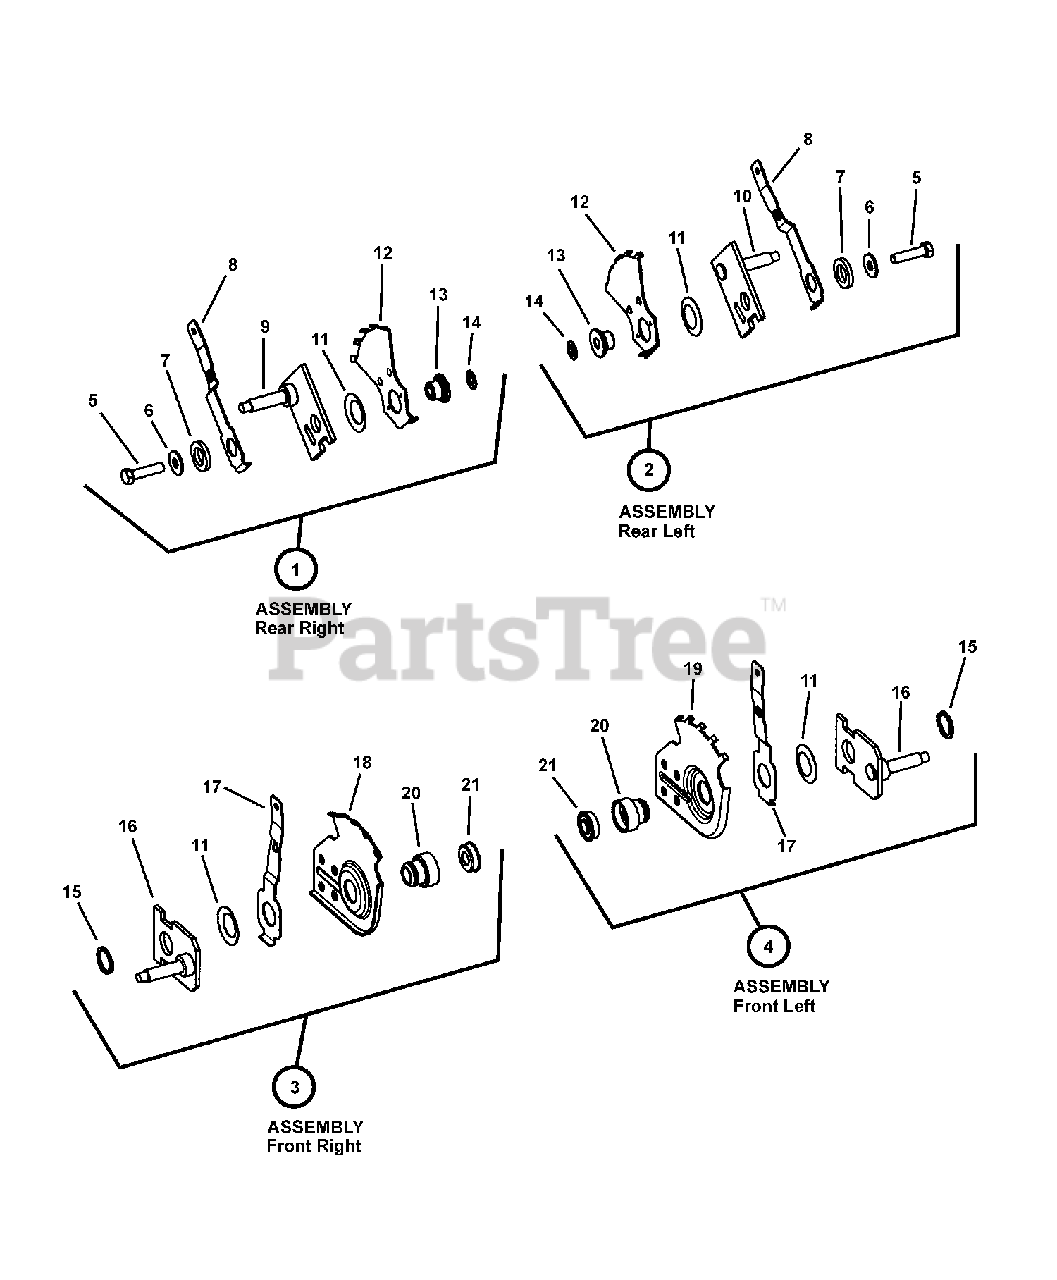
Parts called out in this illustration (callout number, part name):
1	ASSY, HOC, Right Rear, 22" WBM
2	ASSY, HOC, Left Rear, 22" WBM
3	ASSY, HOC, Right Front, 22" WBM, Propelled
4	ASSY, HOC, Left Front, 22" WBM, Propelled
5	SCREW, 3/8-16 x 1-1/2" Hex Head Cap, GR 5, YZ
6	WASHER, .391 x 1 x 14 Gage Flat
7	WASHER, .76 x 1.25 x .180 Flat
8	LEVER, HOC, 22" WBM
9	ASSY, Rear Axle, RH 22" WBM
10	ASSY, Rear Axle, LH 22" WBM
11	WASHER, 1 ID x 1.64 OD Bellville
12	PLATE, Index, HOC, Rear
13	SPACER, Height Adjust
14	RETAINER, 3/8" Bolt
15	RETAINING RING, .906 ID x .078 Thick
16	ASSY, Front Axle 22", Propelled
17	LEVER, HOC, 22" WBM
18	PLATE, HOC, Front Right, 22" WBM
19	PLATE, HOC, Front Left, 22" WBM
20	RETAINER, Bearing
21	BALL BEARING
